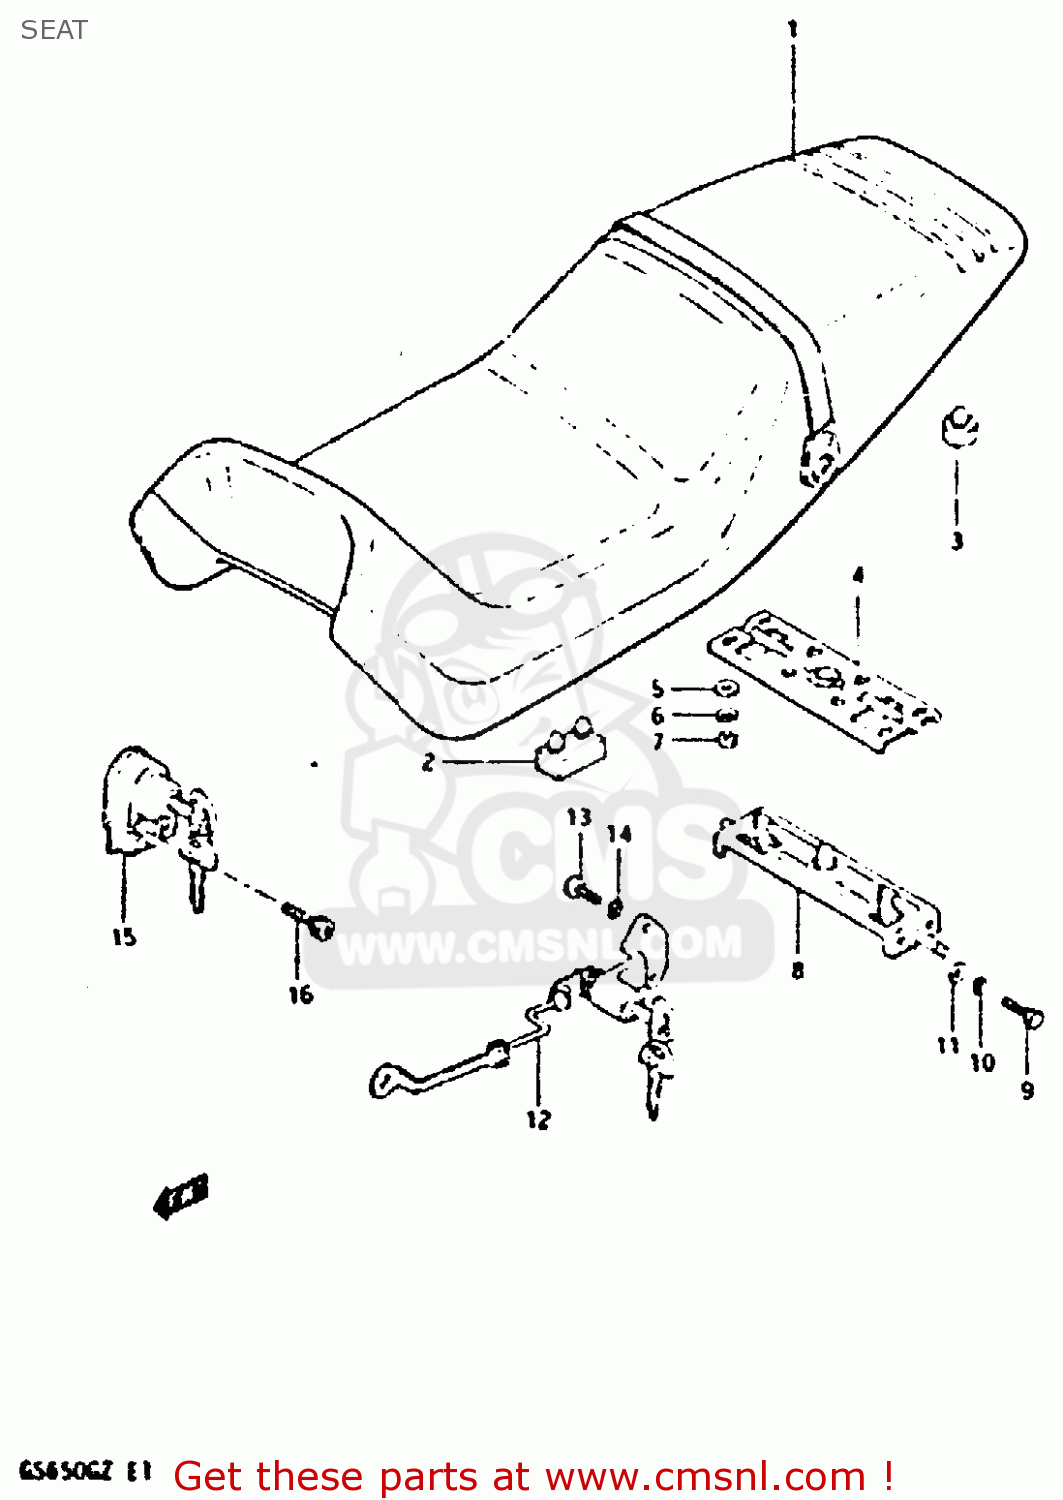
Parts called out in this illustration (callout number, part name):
1	SEAT ASSY
2	CUSHION
3	CUSHION
4	PLATE,SEAT LOCK GUIDE
5	WASHER
6	LOCK WASHER
7	NUT 6MM
8	CLAMP, SEAT
9	BOLT
10	LOCK WASHER
11	WASHER
12	LOCK ASSEMBLY,SEAT
13	BOLT
14	LOCK WASHER
15	LOCK ASSY,HELMET
16	BOLT 5X25
